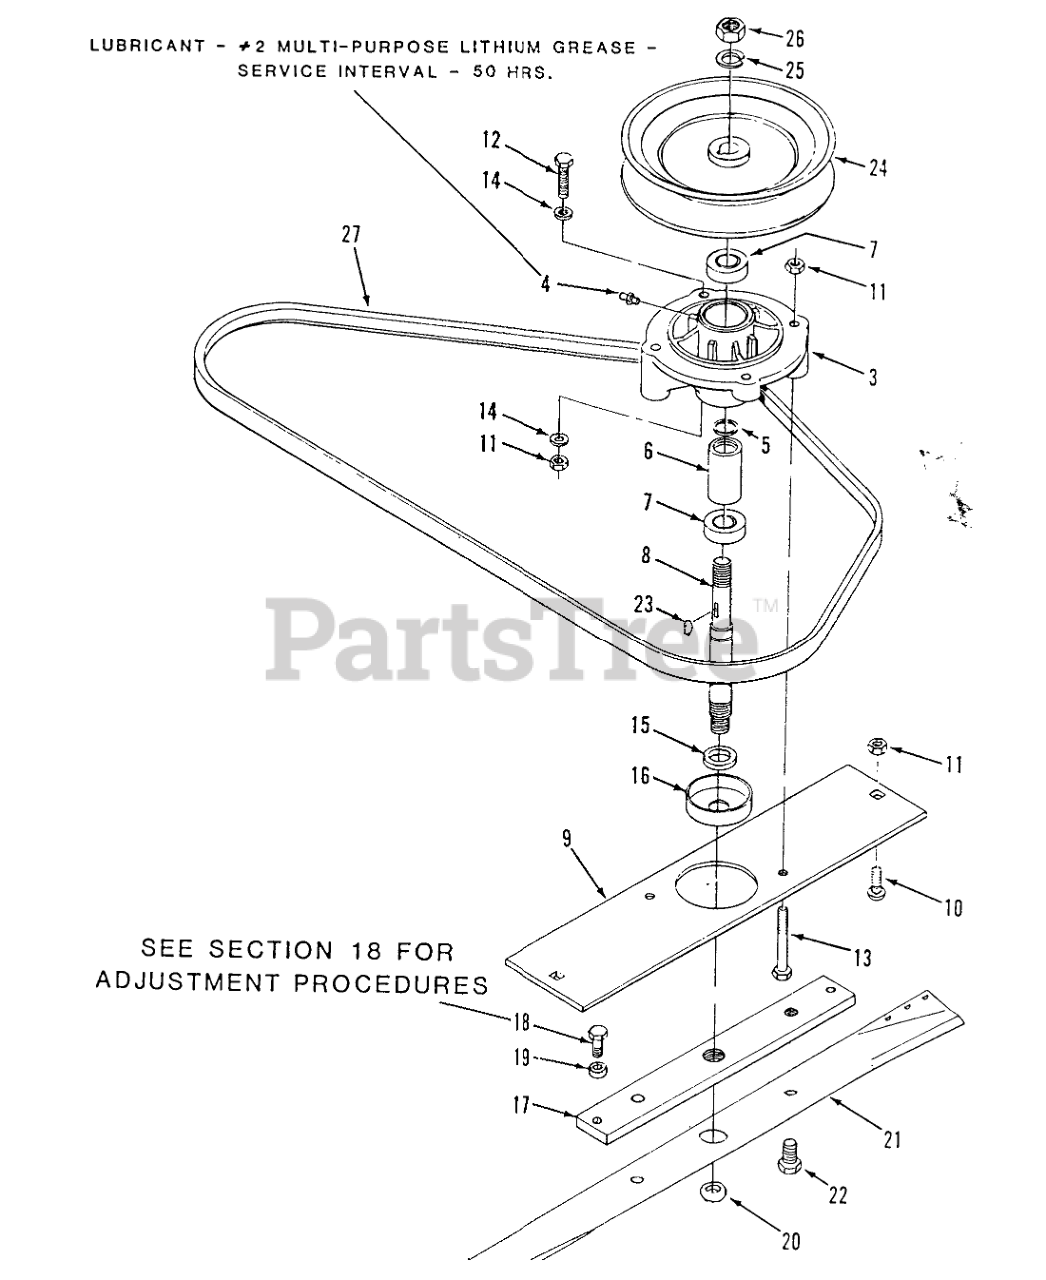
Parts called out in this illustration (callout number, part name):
3	HOUSING-SPINDLE
4	Fitting-Grease
5	SNAP RING
7	BALL BEARING
8	SHAFT
9	BAR R
10	Bolt
11	NUT
12	Bolt
13	Bolt
14	Washer
15	SPACER-BLADE
16	CUP-SPINDLE
17	BAR-BLADE R
18	Bolt
19	NUT-HEX, JAM
20	X-REF 3220-6
21	Blade
22	HEX BOLT 1/2-13X3/4
23	KEY-HI-PRO
24	PULLEY HUB ASSY
25	Lockwasher
26	Nut 5/8-18
27	V-BELT DRIVE
